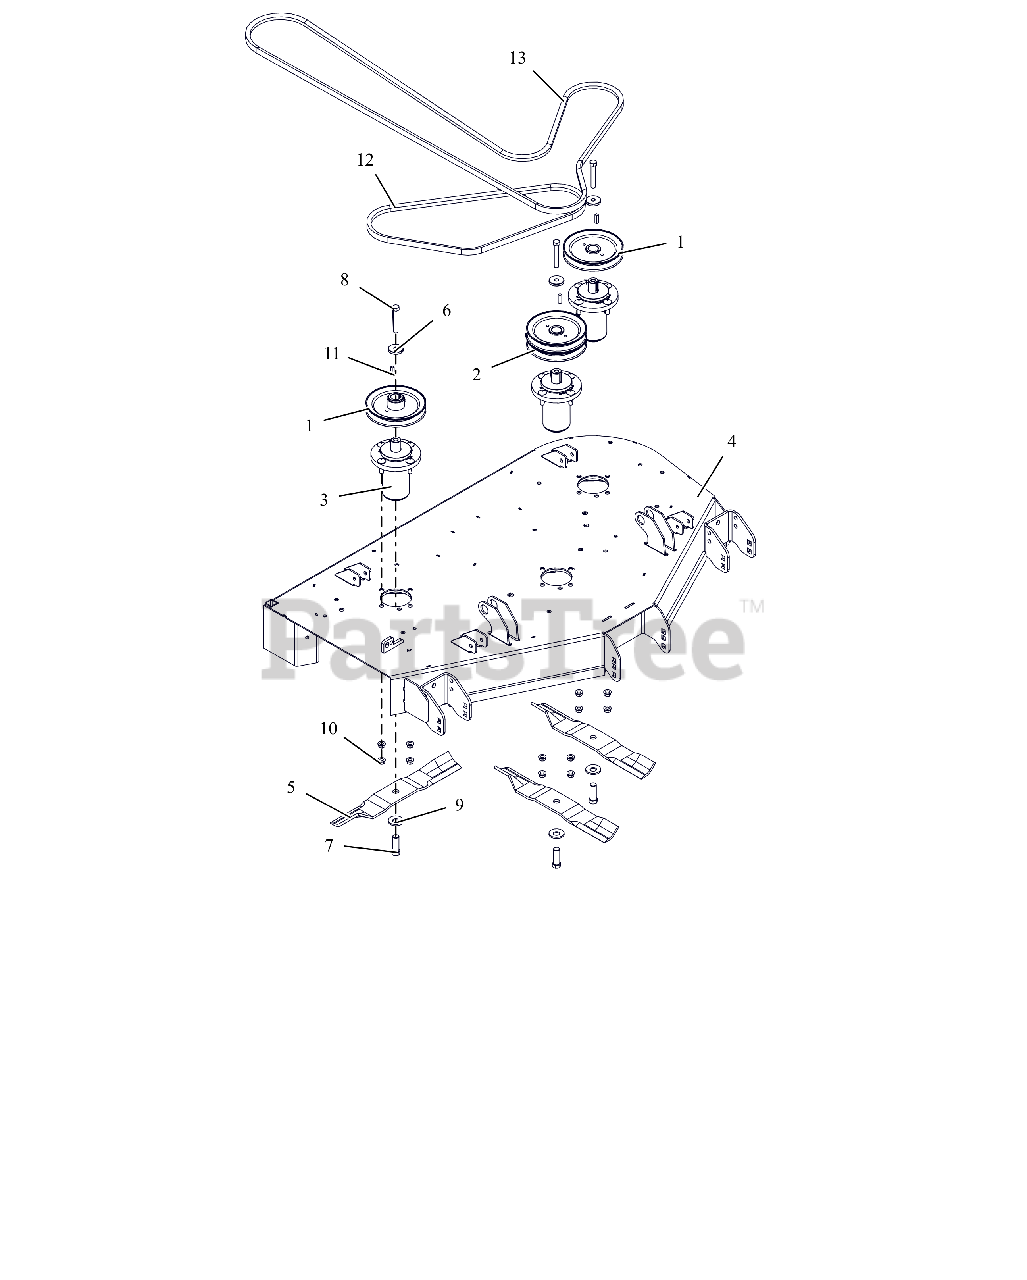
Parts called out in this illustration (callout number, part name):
1	PULLEY, SINGLE-1"ID X 6" OD
2	PULLEY, DOUBLE
3	ASM, MAINT FREE ALUM SPINDLE
4	KIT,DECK-44" W/DECALS -GRAVELY
5	BLADE, 16.19" MOWER (HI-LIFT)
6	RETAINER, SHEAVE
7	BLT, HEX .62-18X1.75 G8 ZCC
8	BLT, HEX 0.4375-20X2.75 G8 ZCC NT
9	WSHR-BLVL .669X1.535X.138
10	NUT-LK-CTR-FLG .375-16 GF ZCC
11	KEY, SQ .25X.25X1.00 RC 40-50
12	V-BELT, B-COGGED
13	V-BELT, HB RAW EDGE EPDM
